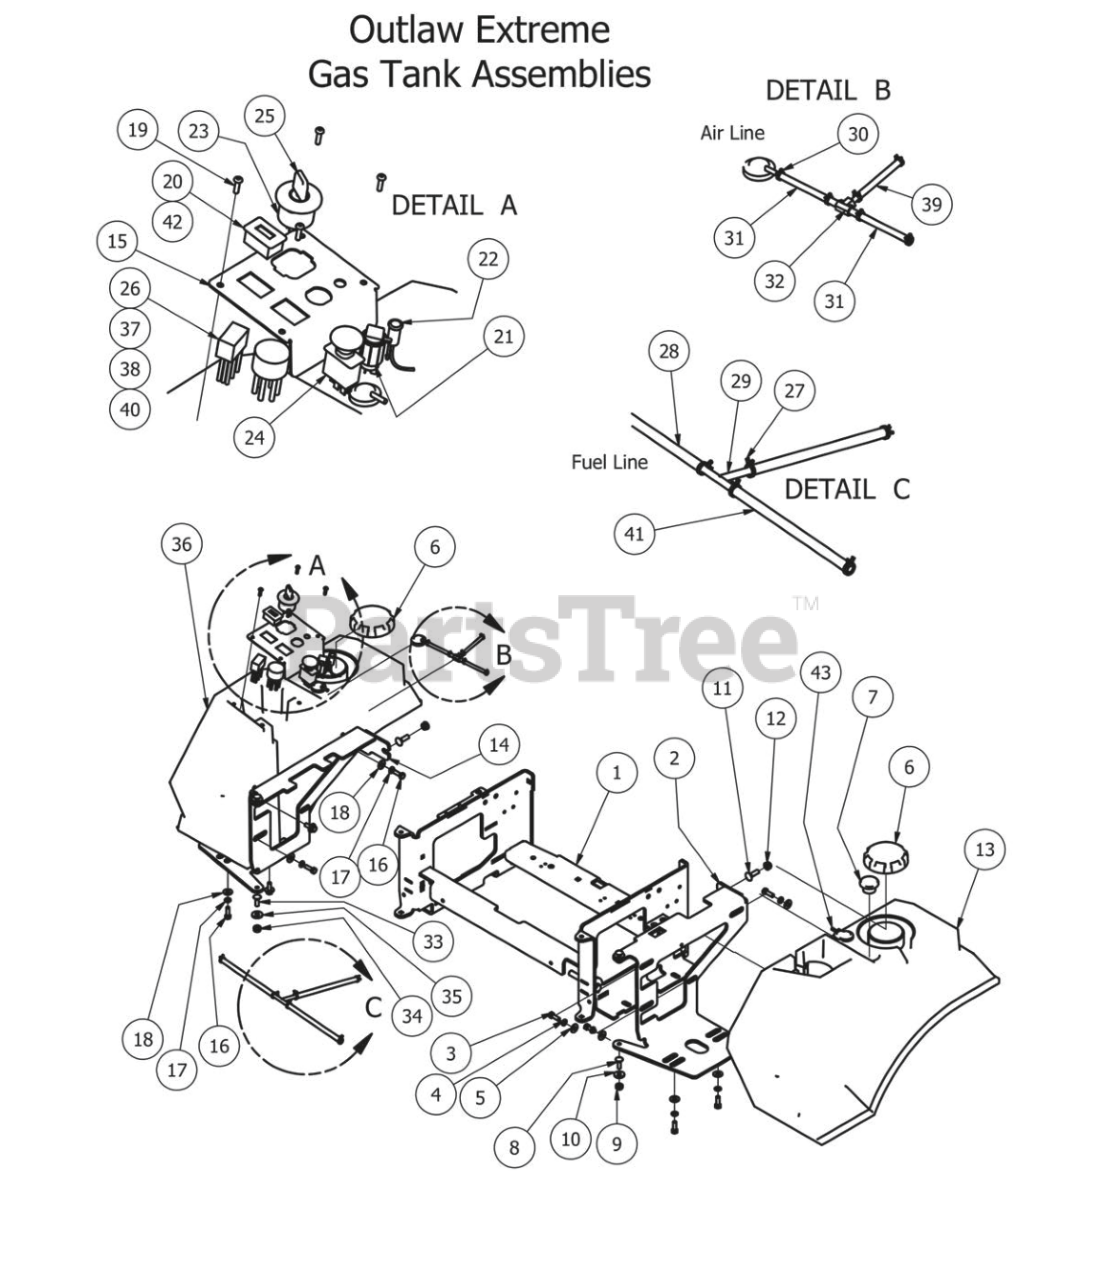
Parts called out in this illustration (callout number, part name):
1	Outlaw Seat Bracket 2012
2	Tank Support 2012 Outlaw (Left)
3	5/16" x 1" Bolt
4	5/16" Lock Washer
5	5/16" Flat Washer
6	3.5" Tethered Fuel Cap
7	Fuel Gauge Tanks W/downtube
8	5/16" x 1" Carriage Bolt
9	5/16-18 Nylon Flange Nut
10	.360 ID Plastic Washer
11	3/8" x 1 1/4" Carriage Bolt
12	3/8" Nylock Flange Nut
13	2012 EPA Fuel Tank- XP-XTRM- Left
14	Outlaw Tank Support 2012 (Right)
15	Outlaw Instrument Panel 2010
16	5/16" x 1" Bolt
17	5/16" Lock Washer
18	5/16" Flat Washer
19	10-32 x 3/8" Button Socket Head Bolt
20	Tachometer
21	12V AUX Connection
23	Ignition Switch
24	PTO Engager
25	Ignition Key
26	Wiring Harness-36hp Outlaw-Vanguard
27	1/4 fuel clamp
28	1/4" fuel line hose
29	fuel line T
30	3/16 vinyl clamp
31	3/16 vinyl tubing
32	Brass fuel line T
33	x 1" Carriage Bolt
34	5/16-18 Nylon Flange Nut
35	.360 ID Plastic Washer
36	2012 EPA Fuel Tank - XP-XTRM - Right
37	Wiring Harness - 31 Kawasaki
38	Wiring Harness - 30 Kohler
39	1/4" Vinyl Tubbing
40	Relay Terminal
41	Fuel line assembly
42	Tachometer-2012 29hp EFI Kohler (only)
